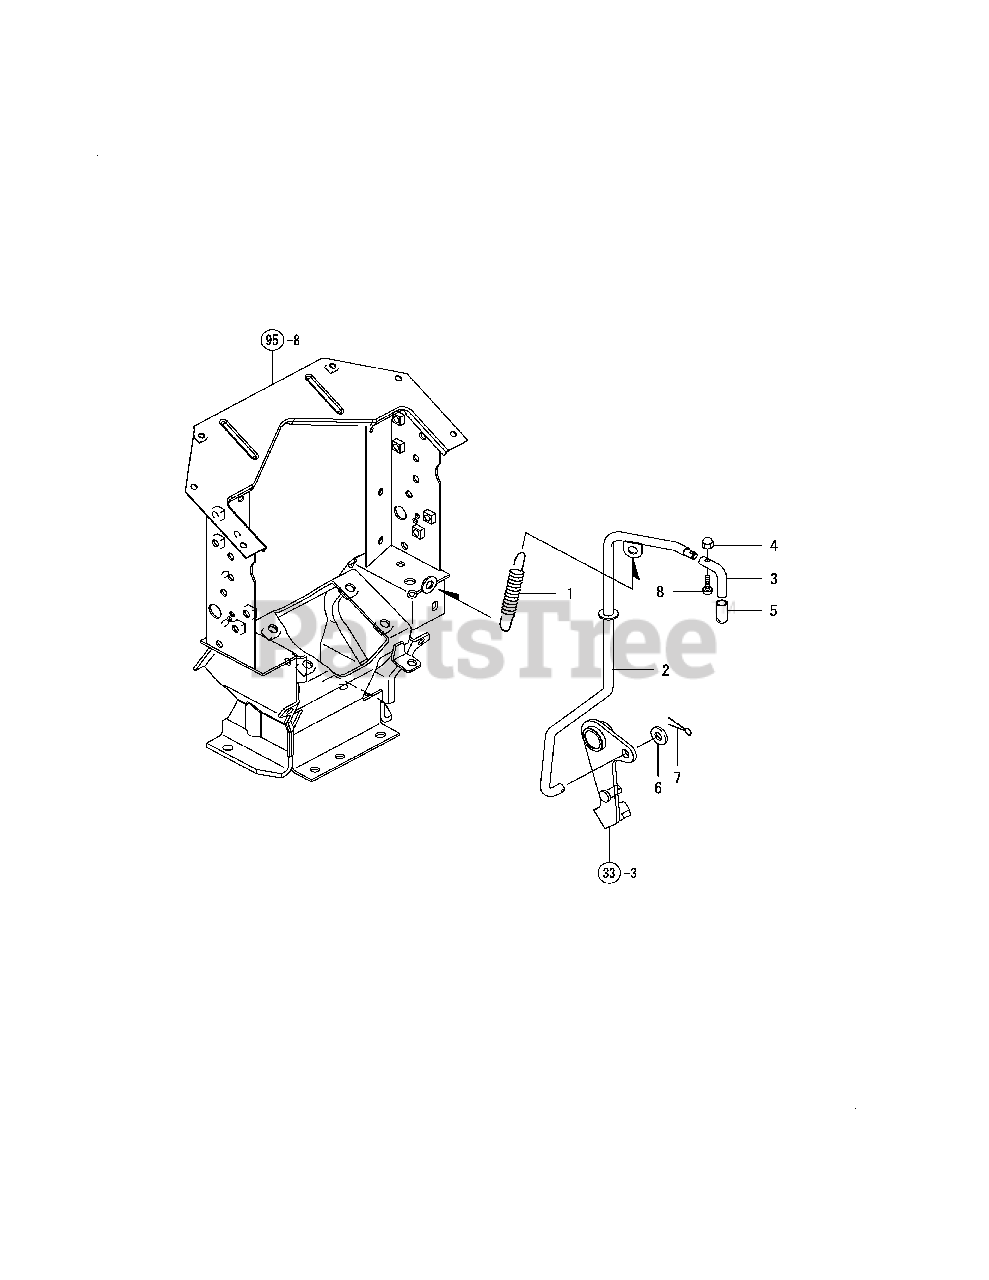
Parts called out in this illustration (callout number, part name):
1	SPRING, RETURN
2	LEVER, CRUISE CMP
3	LEVER B, CRUISE
6	WASHER 10, POLISHED
7	COTTER PIN 2.5X30
